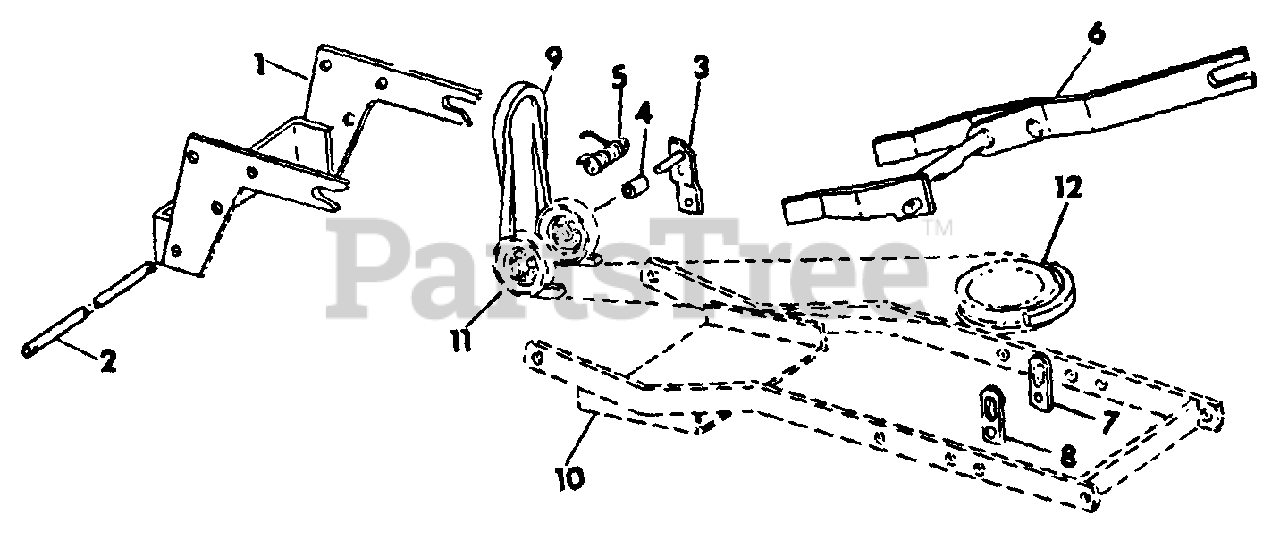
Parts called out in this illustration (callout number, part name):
1	HANGER ASSY, FRONT
2	SHAFT IDLER PIVOT
3	ARM ASSY, RH IDLER
4	SPACER, 3/8 x .896 STD PIPE
5	SPRING, MULE DRIVE IDLER
6	FRAME ASSY, CENTER
7	LINK, LH LIFT
8	LINK, RH LIFT
9	BELT, MULE DRIVE
10	FRAME ASSY, OUTER LIFT
11	PULLEY, DRIVE BELT IDLER
12	PULLEY, CENTER
